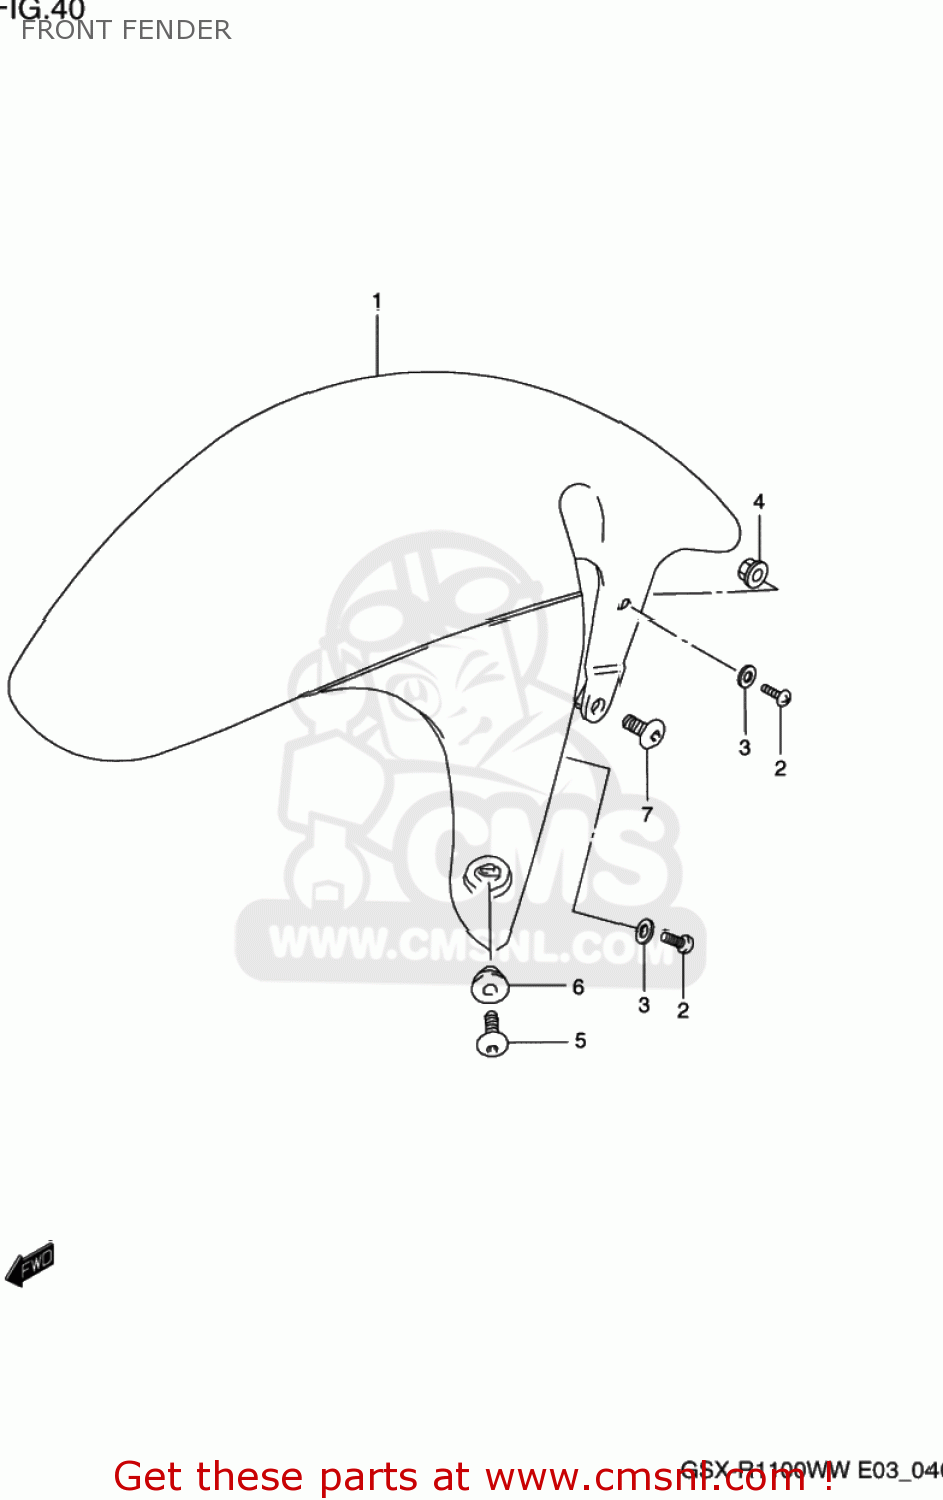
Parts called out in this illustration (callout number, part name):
1	FENDER,FR
2	SCREW
3	WASHER
4	NUT
5	SCREW(6X16)
6	WASHER(6.3X16X1.5)
7	BOLT
